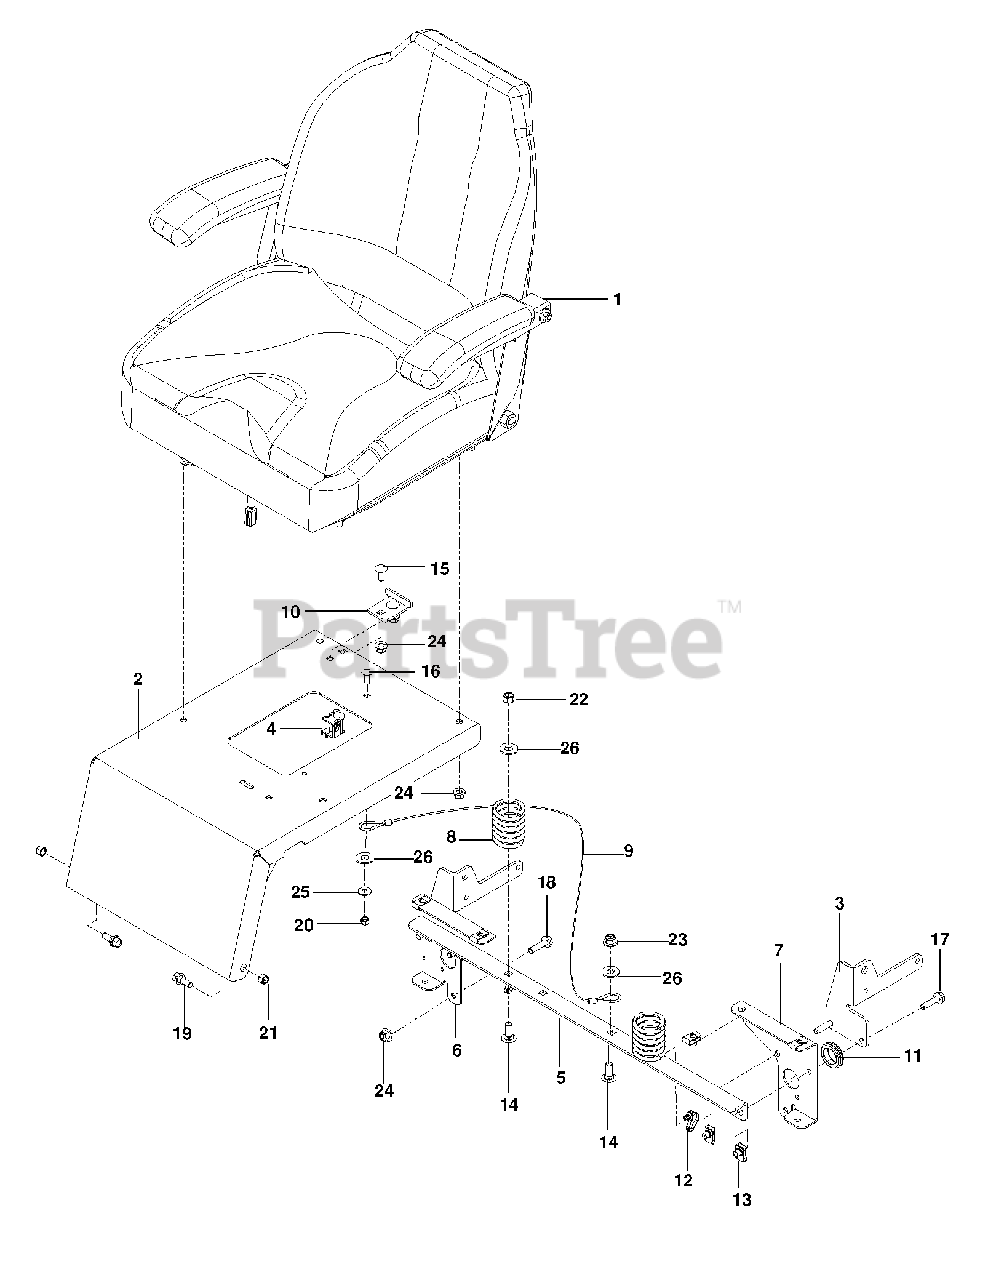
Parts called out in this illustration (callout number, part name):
2	SEAT MOUNT, W/DECALS
3	MOUNT, SEAT BELT, BLACK
4	SEAT SWITCH
5	SUPPORT, SEAT
6	SUPPORT, RT, BLK
7	SUPPORT, LT, BLK
8	SPRING, SEAT
9	SEAT LANYARD
10	STOP, SEAT - BLACK
12	TIE WRAP, 8-3/8", W/CLIP
13	U-CLIP 5/16-18 NUT RETAINER
14	RHSNB 3/8C X 1
15	RHSNB 5/16-18 X 3/4
16	RHSNB 1/4C X 3/4
17	HHFS 5/16-18 X 1.25 TPBLT GD 5
19	SB 5/16-18 HEX HD GD5, BLK ZN
20	NUT 1/4-20 NYLOC
21	NUT 5/16 NYLOC
22	NUT 3/8-16 NYLOC
23	NUT 3/8-16 HEX FLG NYLOC ZD
24	5/16-18 NYLOC FLANGE NUT
25	WASHER 1/4 FLAT
26	WASHER 3/8 FLAT
